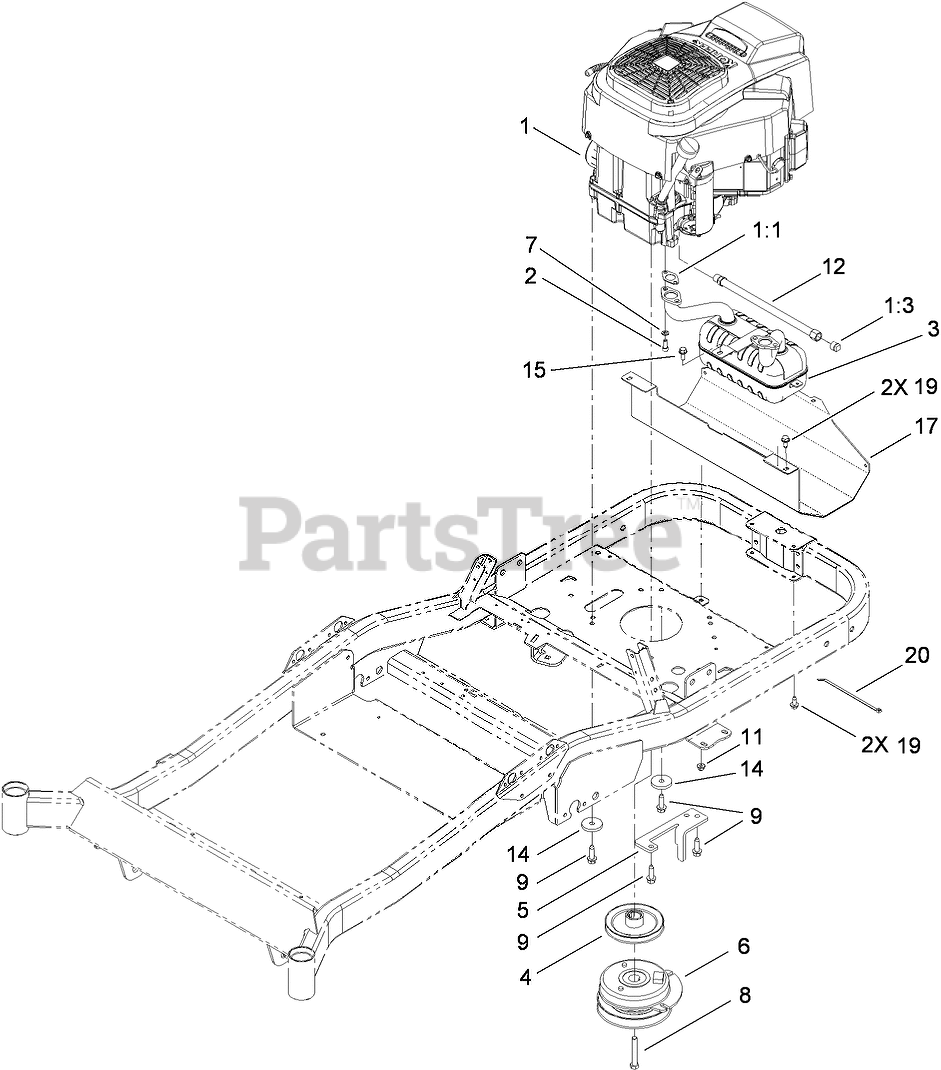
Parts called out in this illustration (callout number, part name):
1:1	GASKET-EXHAUST
1:3	PLUG-PIPE, SQH
2	SCREW-HSH
3	MUFFLER-TWIN, KOHLER
4	PULLEY-ENGINE
5	BRACKET-STOP, PTO
6	CLUTCH-PTO
7	WASHER-LOCK
8	SCREW-HH
9	SCREW-TAPTITE
11	NUT-HF, NI
12	HOSE-DRAIN, OIL
14	WASHER-PLAIN
15	SCREW-HHF
17	SHIELD-HEAT
19	SCREW-HWHTF
20	TIE-CABLE
